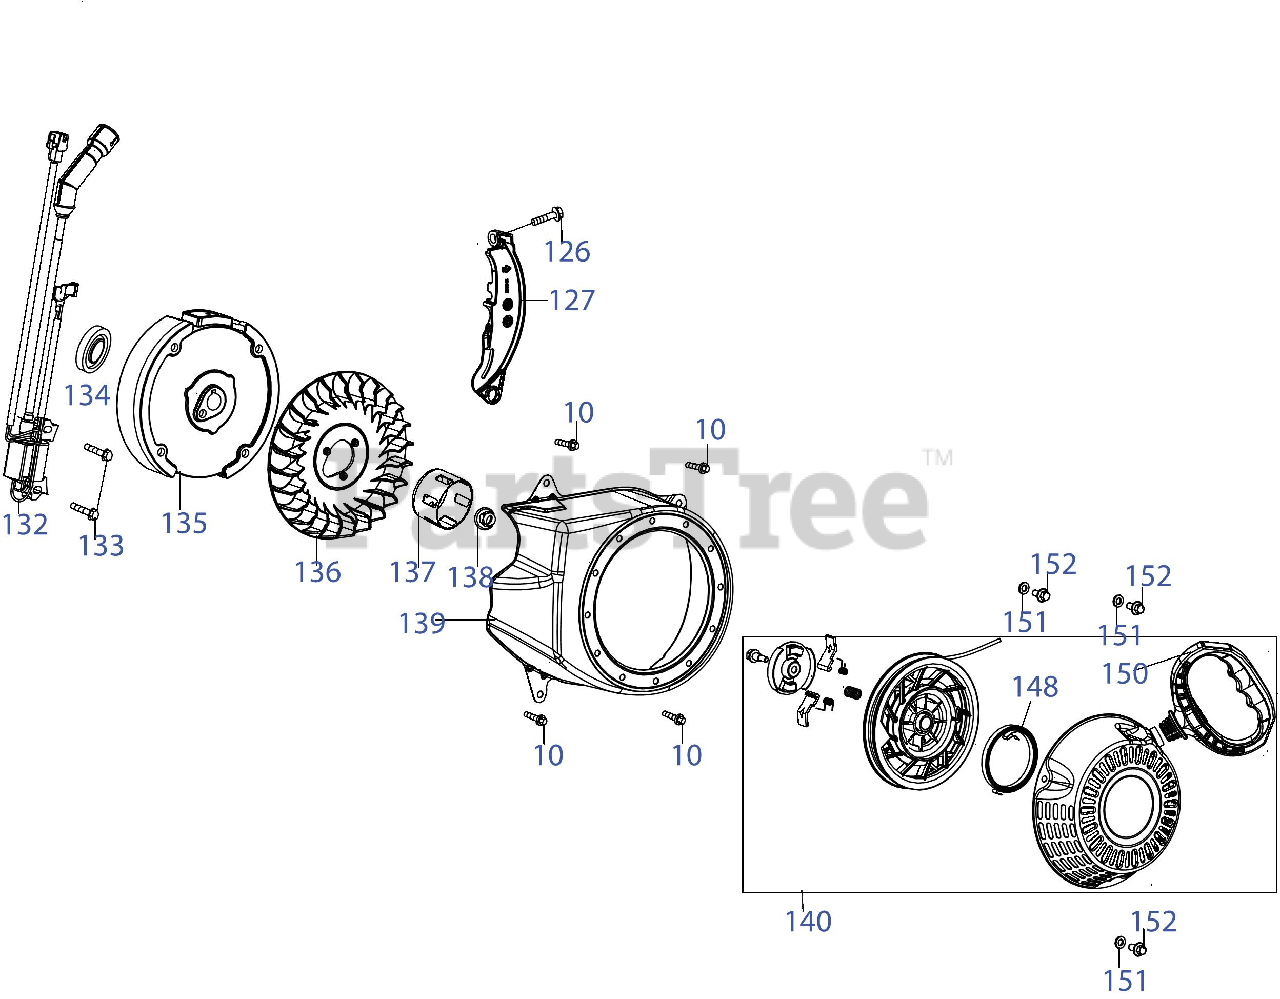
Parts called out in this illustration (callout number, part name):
10	Bolt M6x12
126	Bolt M6x20
127	Lower Shield
132	Ignition Module
133	Bolt M6x25
134	Oil Seal 25x41.25x6
135	Flywheel
136	Cooling Fan
137	Pulley, Starter
138	Flange Nut M14x1.5
139	Blower Housing
140	Recoil Starter
148	Recoil Spring
150	Starter Handle
151	Washer 6
152	Bolt M6x12
